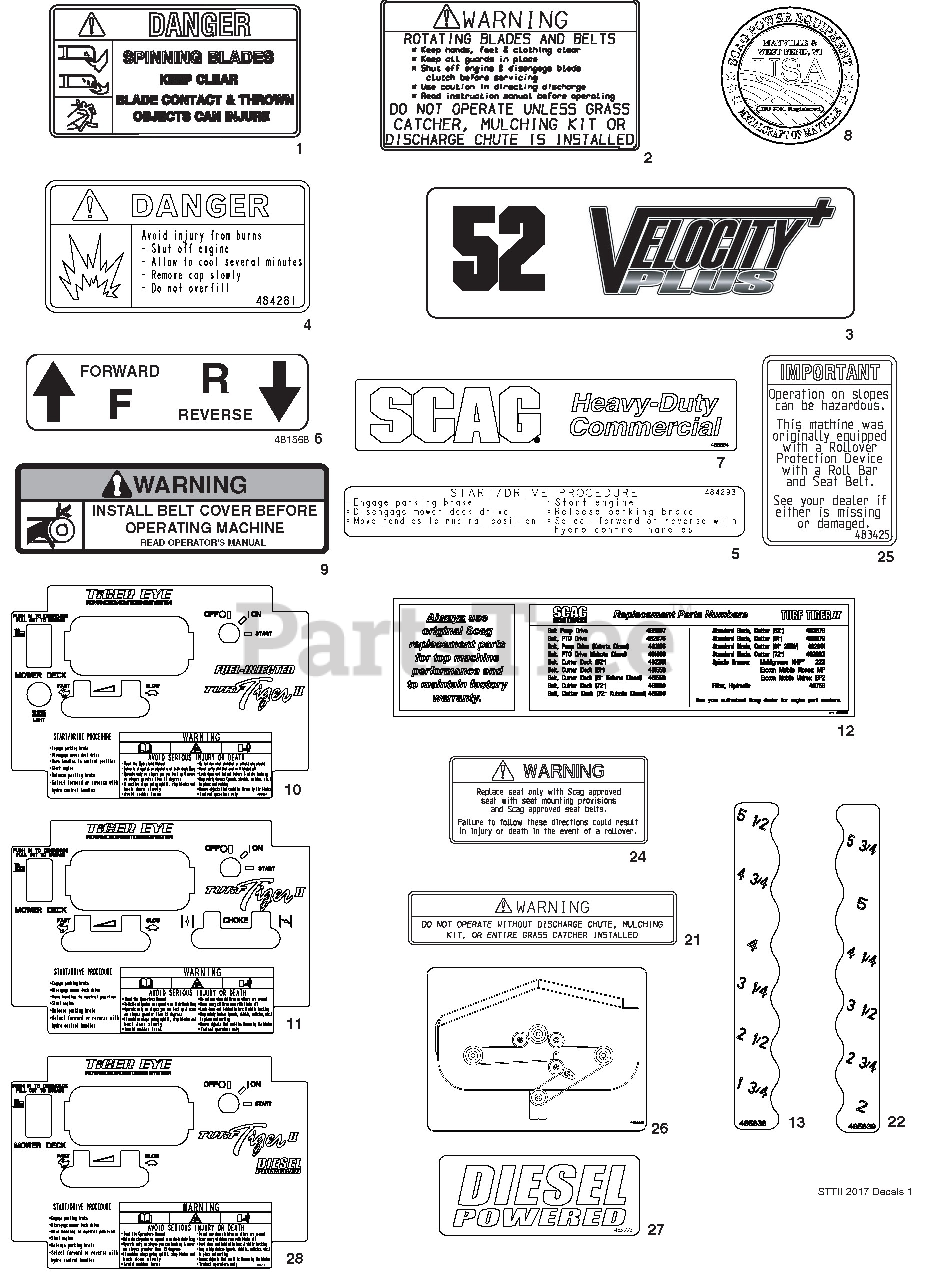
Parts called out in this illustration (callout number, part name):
1	Decal, Danger - Spinning Blades
2	Decal, Warning - Rotating Blades
3	Decal, 52 Velocity Plus
3	Decal, 61 Velocity Plus
3	Decal, 72 Velocity Plus
4	Decal, Fuel Tank - Gasoline Engines
4	Decal, Fuel Tank - Kubota Diesel
5	Decal, Start / Drive
6	Decal, Traction Control
7	Decal, Heavy-Duty Commercial
8	Decal, Metalcraft - USA
9	Decal, Belt Cover
10	Decal, Instrument Panel - Fuel Injected
11	Decal, Instrument Panel
12	Decal, STTII Replacement Parts
13	Decal, Cutting Height - LH
21	Decal, Warning
22	Decal, Cutting Height - RH
24	Decal, Seat Replacement
25	Decal, ROPS
26	Decal, Belt Routing
27	Decal, Diesel Powered - Kubota Diesel
28	Decal, Instrument Panel - Kubota Diesel
